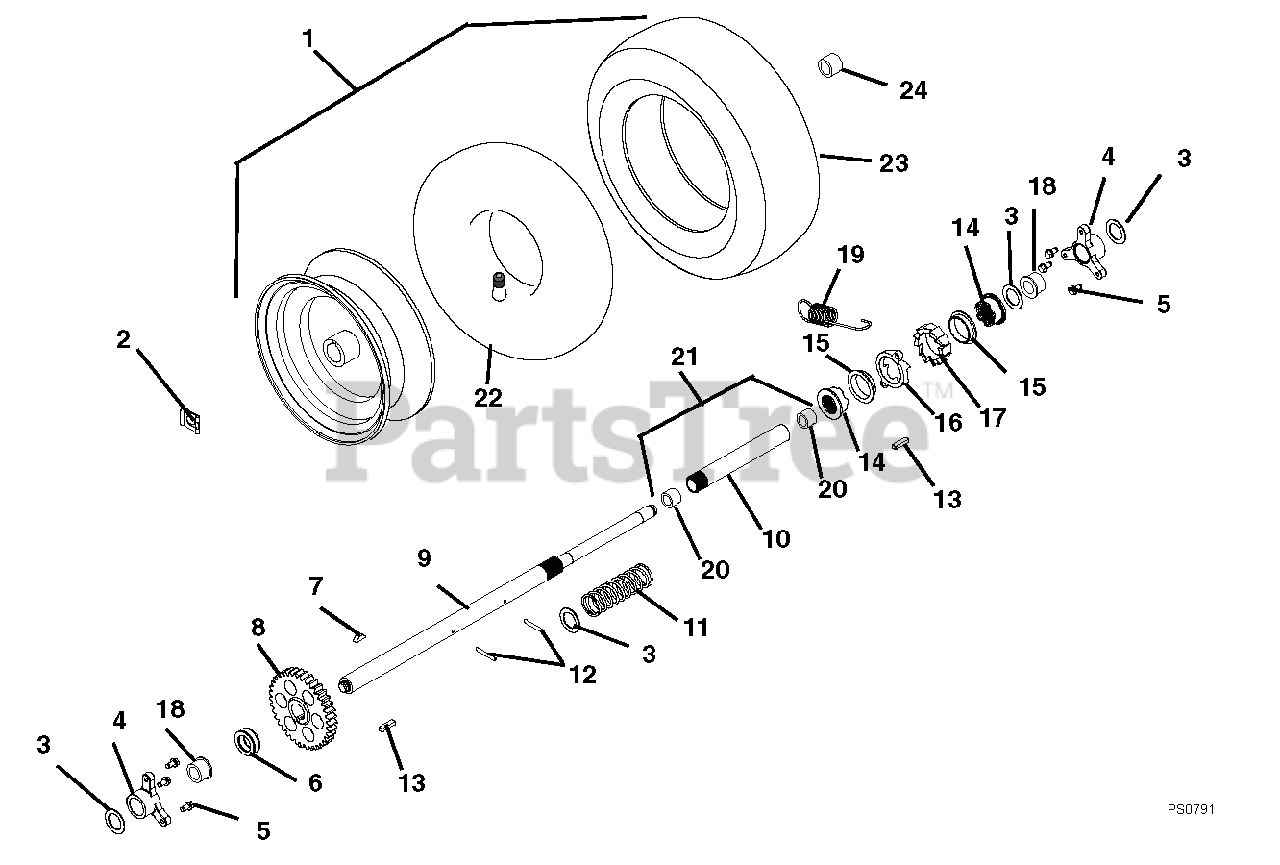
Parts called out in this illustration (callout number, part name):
1	TIRE/WHEEL, RH 16X6.50-8 DIFF
2	CLIP, SNAP .625 DIA
3	WSHR-FL-STL 1.010X1.505X.062YZ
4	BUSHING, RAKE SHAFT 1"
5	SCR-TAP .25-20X.50 HWH TR YWZ
6	SPACER 1.008X1.503X.605
7	KEY-WDRF .25X.750X.313 SAE91
8	GEAR, SPUR
9	AXLE, DIFFERENTIAL-LONG
10	AXLE, DIFFERENTIAL-SHORT
11	SPRING, COMPRESSION
12	PIN-ROLL .188X1.50
13	KEY-RECT .25X.188X1.00
14	CLUTCH, DOG - SLIDING
15	BUSHING, FLANGE
16	GEAR, CLUTCH
17	GEAR, RATCHET
18	BSHG-FLG SPLIT NYLINER 1.0" HP
19	SG-TENS .06X.62X2.94
20	BSHG-SLV .706X.764X.75 BRZ
21	AXLE, DIFFERENTIAL-W/BUSHINGS
23	TIRE, 16X6.50-8 K478
24	SPACER, 1.010X1.50X.61
